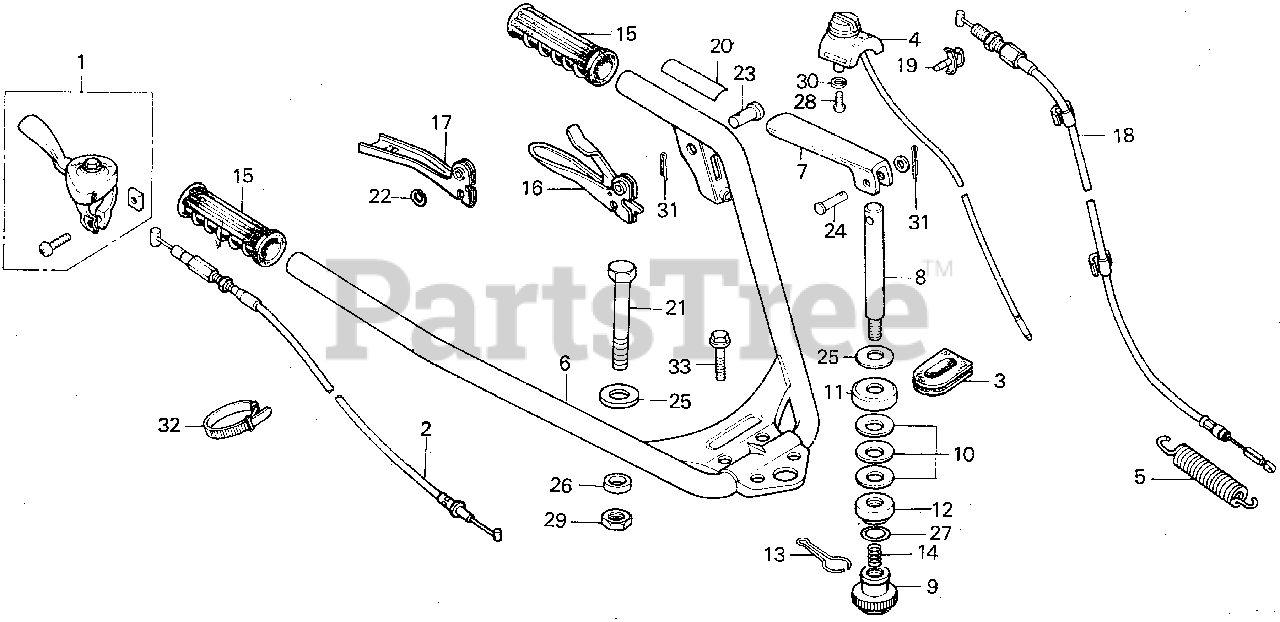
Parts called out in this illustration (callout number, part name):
1	LEVER ASSY., THROTTLE
2	CABLE, THROTTLE
3	GROMMET, WIRE
4	SWITCH ASSY., STOP
5	SPRING, LOCK
7	LEVER, HANDLE ADJUSTING
8	SHAFT, HANDLE ADJUSTING
9	NUT, HANDLE ADJUSTING
10	SPRING, HANDLE ADJUSTING
11	SHEET, HANDLE ADJUSTING SPRING
12	COLLAR, ADJUSTING
13	HOLDER, NUT
14	SPRING, LOCK
15	GRIP, HANDLE
16	LEVER, CLUTCH (NOT AVAILABLE)
18	CABLE, CLUTCH (NOT AVAILABLE)
20	CAUTION, CLUTCH LEVER
23	PIN (8X18)
24	PIN, ARM (NOT AVAILABLE)
25	WASHER, THRUST (14)
27	O-RING (58.5X2)
28	SCREW, PAN (3X12)
30	WASHER, SPRING (3MM)
31	PIN, COTTER (2.0X15)
32	BAND B1, CABLE
33	BOLT, FLANGE (6X16)
